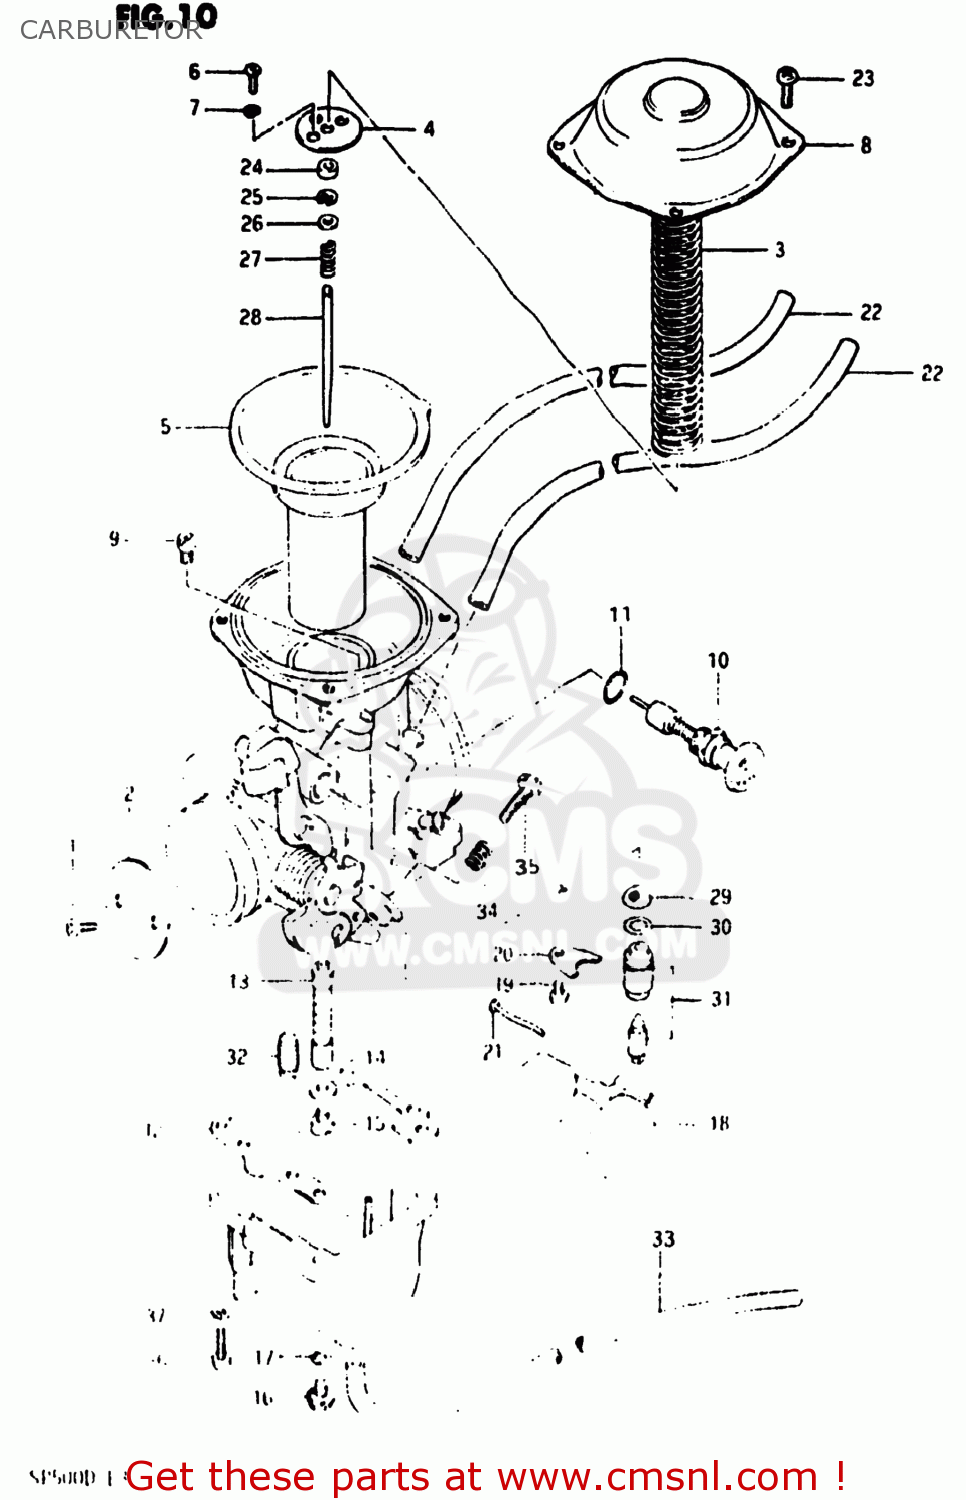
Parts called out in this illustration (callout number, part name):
1	SCREW
2	VALVE,THROTTLE (BUTTERFLY)
3	SPRING,DIAPHRAGM
4	PLATE
5	DIAPHRAGM ASSEMBLY
6	SCREW
7	LOCK WASHER
8	COVER
9	JET
10	PLUNGER
11	O RING
12	GASKET,FLOAT CHAMBER (NAS)
13	JET,NEEDLE
14	WASHER
15	JET,MAIN(140)
16	PLUG,DRAIN
17	GASKET (NAS)
18	FLOAT
19	SCREW 4X6
20	PLATE
21	PIN,FLOAT
22	HOSE
23	SCREW
24	RING
25	CLIP,NEEDLE
26	WASHER
27	SPRING
28	NEEDLE JET
29	FILTER
30	O RING
31	VALVE ASSEMBLY,NEEDLE
32	JET,PILOT
33	HOSE
34	SPRING
35	SCREW,THROTTLE STOP
36	SCREW
37	LOCK WASHER
